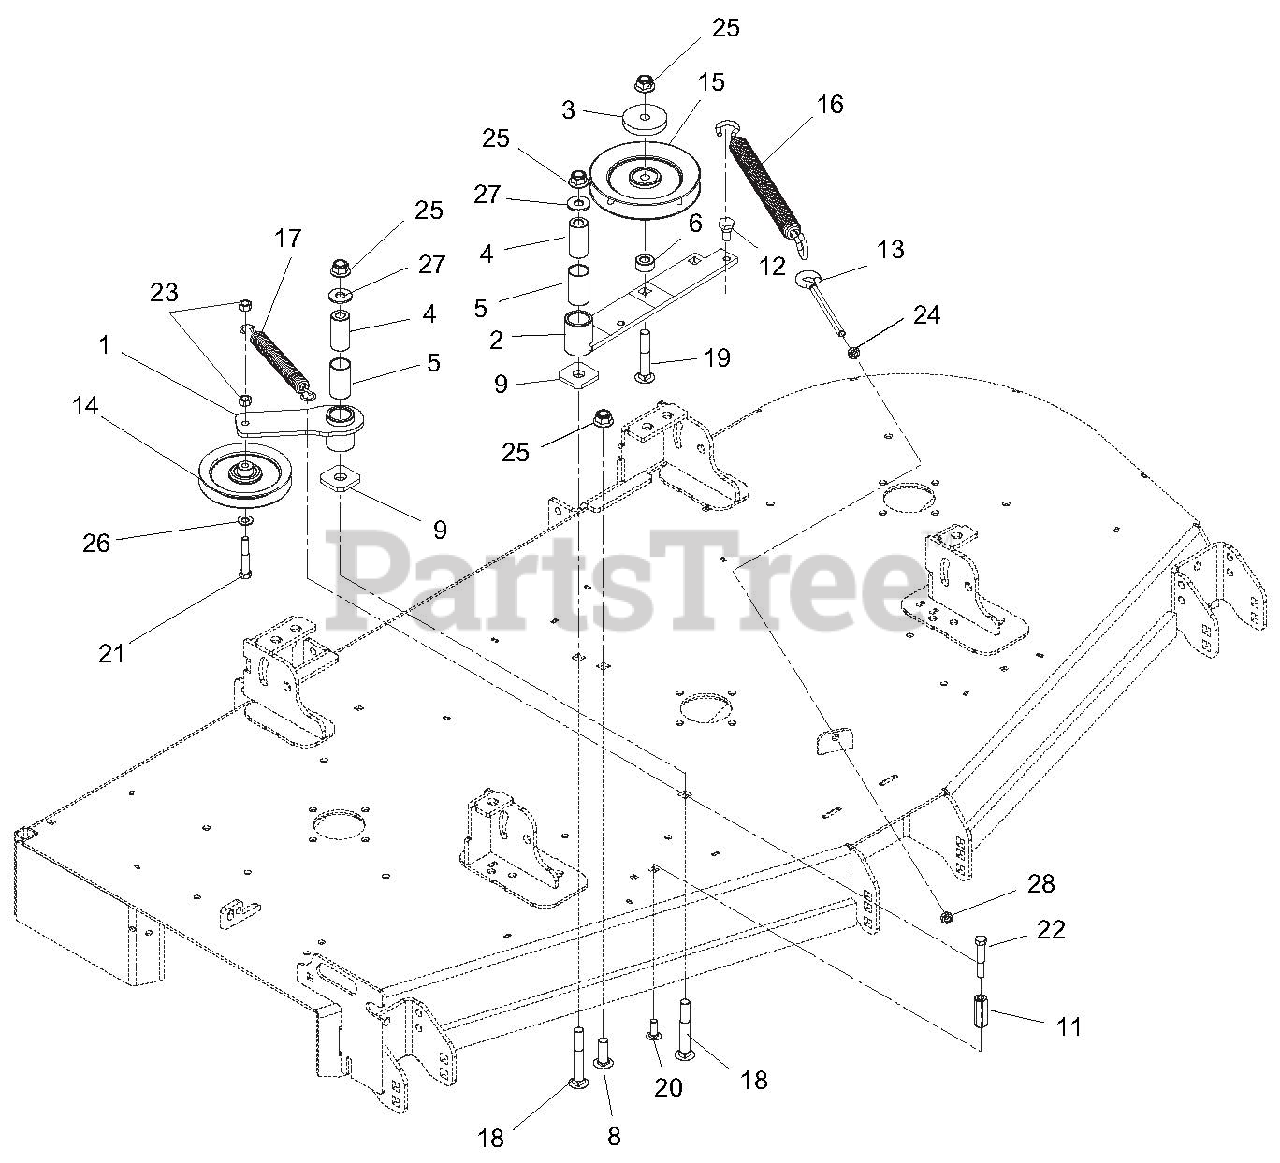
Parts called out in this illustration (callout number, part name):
1	WMT, IDLER PIVOT ARM
2	WMT, IDLER PIVOT ARM
3	CAP, IDLER BEARING SEALING
4	BSHG, SPCR .502X.997X2.03
5	BSHG, 1.00X1.125X1.937
6	BSHG, SPCR .502 X .997.50 PM
8	BLT, RNHDSQSHNK 1/2-13 X 2.00 FULL
9	WSHR, -FLT.640X1.75X.250
11	NUT-HEX COUPLING
12	BLT, SHLDR EP .38-16X.30 HEX
13	BOLT, .38-16X6.00 .62 DIA EYE
14	SHV, .38" ID X 5.0’’ OD V-IDLER
15	SHEAVE, .50" ID X 6.00" OD V-IDLER
16	SPRG, EXTENSION
17	SPRG, EXT. .845 X 6.55
18	BLT-RDHDSQNK .50-13X3.50 G5
19	BLT-RDHDSQNK .50-13X3.00 G5
20	BLT-RDHDSHSQNK.38-16X1.0 G5YZ
21	BLT-HEX .38-16X2.25 GR5 YWZC
22	BLT-HEX .38-16X1.75 GR5 YWZC
23	NUT-LK-CTR .38-16 YWZC
24	NUT, 3/8-16 JAM GR5
25	NUT-LK-NYL-FLG .50-13 YWZC
26	WSHR-FL-STL.406X.812X.065 YWZ
27	WSHR-FL-STL.563X1.38X.109YWZC
28	NUT-LK-CTR JAM .375-16
